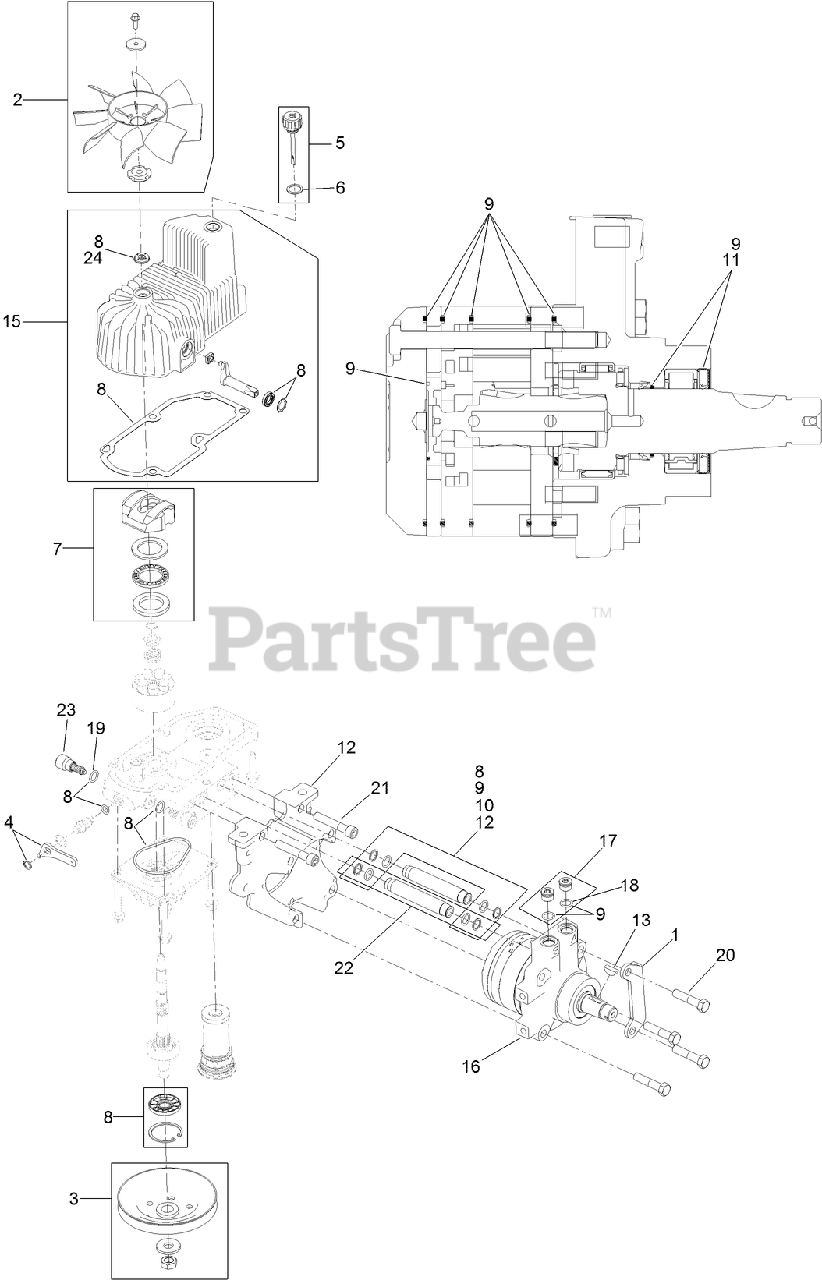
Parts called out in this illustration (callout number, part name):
1	MOUNT-SHOE, HORSE
2	FAN KIT
3	PULLEY KIT
4	HANDLE-BYPASS VALVE, HYDRO
5	DIPSTICK-HYDRO W/GASKET
6	GASKET-DIPSTICK, HYDRO
7	SWASH BLOCK KIT
8	PUMP SEAL KIT
9	MOTOR SEAL KIT
10	TUBE SEAL KIT
11	OUTPUT SHAFT SEAL KIT
12	NOSE CUP-UHT
13	KEY-WOODRUFF
15	Housing-RH
16	MOTOR-HYDRAULIC, RH 280CC
17	MAGNETIC PLUGS SERVICE KIT
18	O-RING
19	O-RING-CHECK VALVE
20	SCREW HH
21	SCREW-HSH
22	HYDRAULIC TUBE KIT
23	SHOCK VALVE, 16CC HYDRO
24	SEAL-FAN DRIVE
